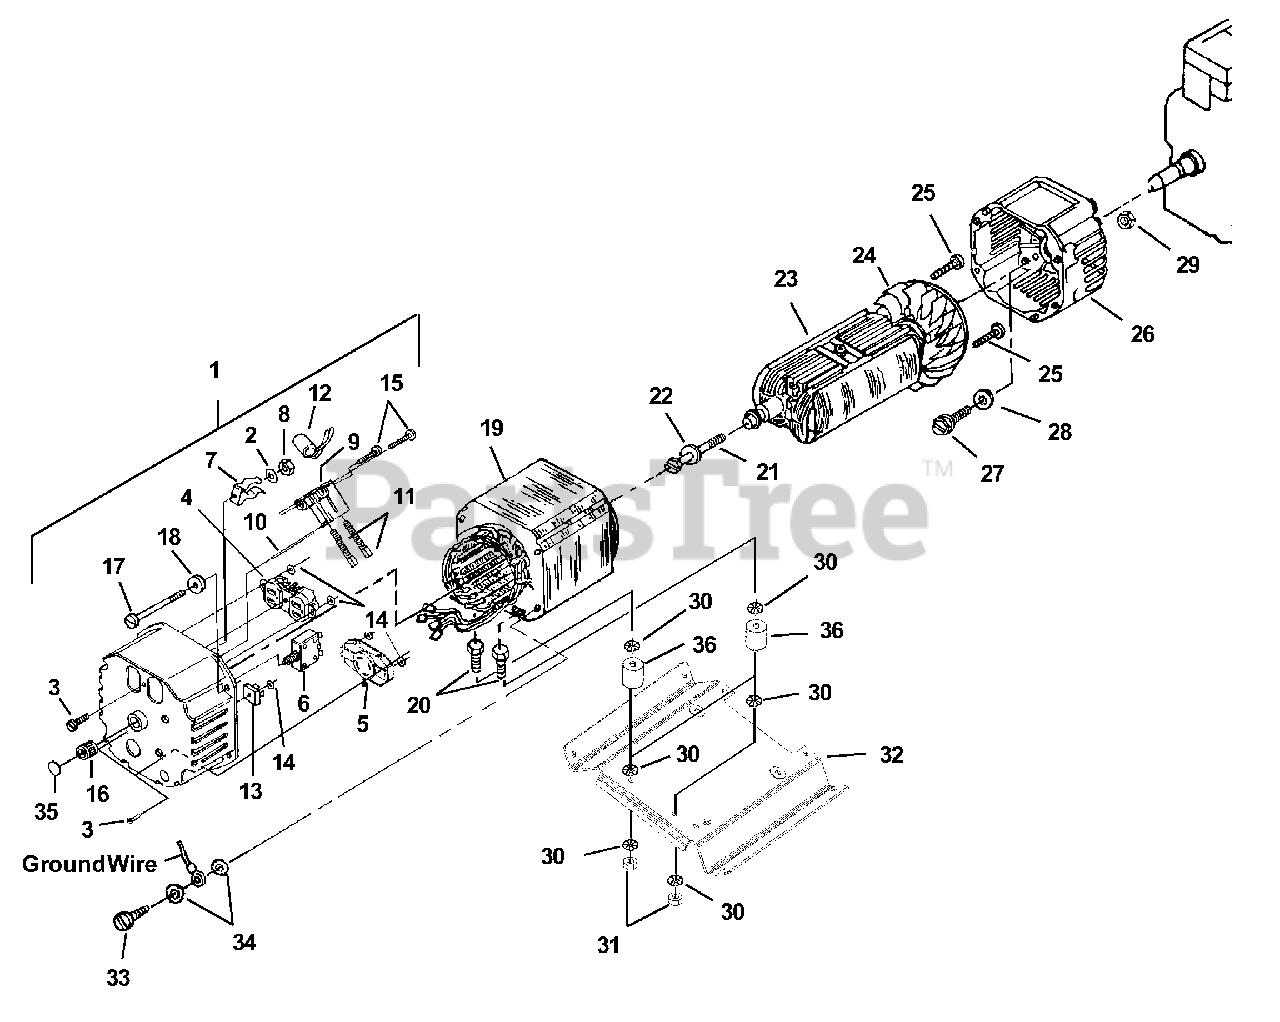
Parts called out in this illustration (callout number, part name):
1	COMPLETE BRUSH HEAD
2	WASHER - Lock (ext.)
3	SCREW - Mach. Pan Hd. (6-32 X 1/2")
4	RECEPTACLE - Duplex (Nema 5-20R)
5	RECEPTACLE - Locking (120V/240V) (Nema L14-20R)
6	BREAKER - Circuit (20 amp.)
7	CLIP - Spring Cap
8	NUT - Hex (6-32)
9	BRUSH HOLDER
11	BRUSH
12	CAPACITOR (w/Lead)
13	RECTIFIER
14	WASHER - Shaft Retention
15	SCREW - Pan Hd. (6-19 X 3/4 )
16	BEARING - Needle
17	BOLT - Stator
18	WASHER - Flat
19	STATOR
20	SCREW - Hex Hd. (5/16-18 X 1 3/4")
21	BOLT-Rotor
22	WASHER - Lock (5/16")
24	FAN - Generator
25	SCREW - Pan Hd. (6-19 X 3/4")
26	END BELL
27	SCREW - Hex Hd. (5/16-24 X 3/4")
28	Washer - Lock
29	Nut - Hex (1/4-20)
30	Washer - Lock (int./ext.)
31	Nut - Hex (5/16-18)
32	Sub - Frame
33	Screw - Taptite (10/24 X 3/4")
34	Washer - Lock (int./ext.)
35	Plug - Expansion
